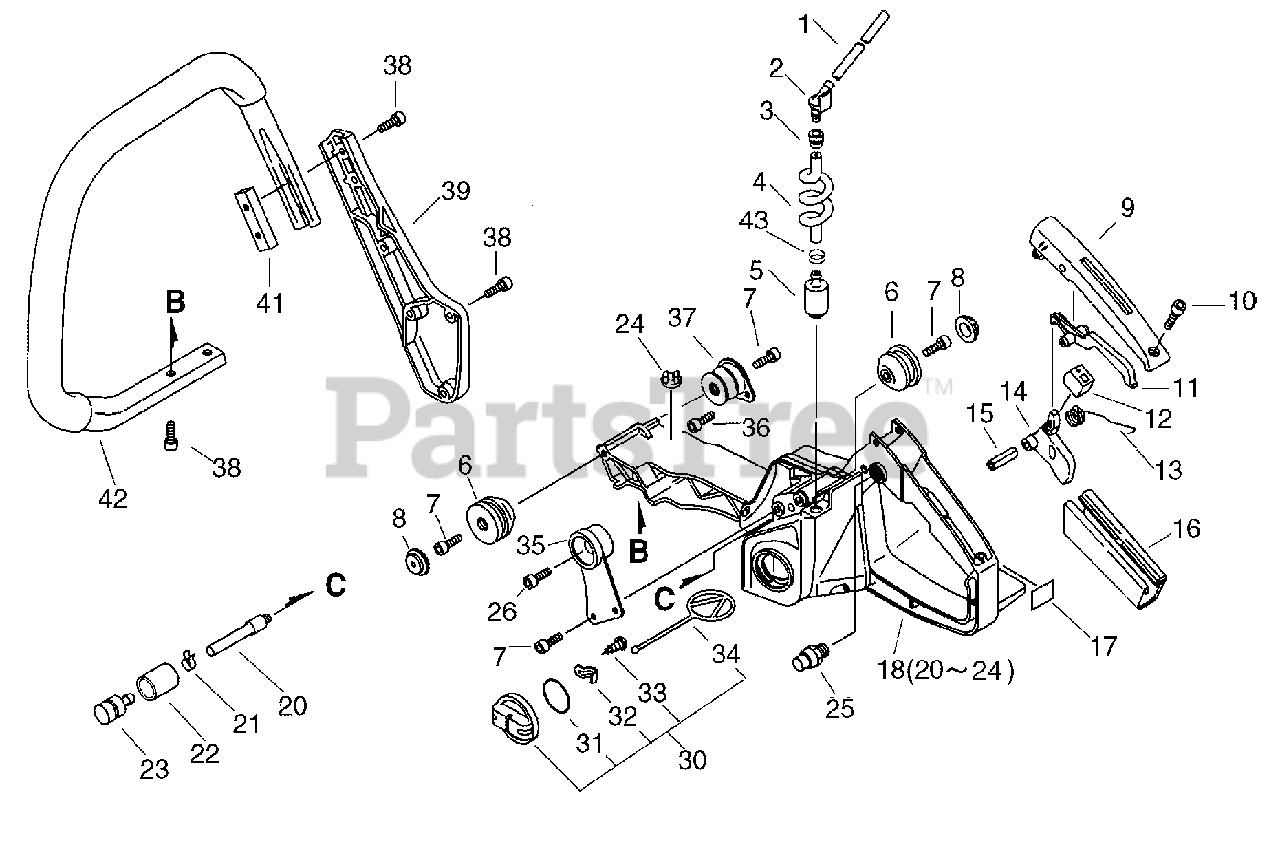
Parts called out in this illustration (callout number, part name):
1	PIPE - 3X6X120 -- BLACK
2	CONNECTOR, PIPE
3	GROMMET
4	PIPE - BLACK
5	FILTER, FUEL
7	SCREW - 5X14
8	CAP, CUSHION
9	COVER, HANDLE
10	SCREW - 4X14
11	LOCKOUT, THROTTLE
12	CUSHION, THROTTLE
13	SPRING, TRIGGER
14	TRIGGER, THROTTLE
15	PIN - SPRING -- 5X25
16	GRIP, HANDLE
17	LABEL - STOP
18	HANDLE ASSY - REAR -- ORANGE
20	PIPE - 3X5X55 -- BLACK
21	CLIP - 5.5
22	COVER, VENT
23	VENT, FUEL TANK
25	LATCH, THROTTLE
26	SCREW - 5X20
30	CAP ASSY
31	O-RING - 29
32	RETAINER
33	SCREW - 3X8
34	CONNECTOR, CAP
36	SCREW - 4X10
38	SCREW - 5X20
39	BRACKET, HANDLE
42	HANDLE - FRONT
43	CLIP - 6.5
